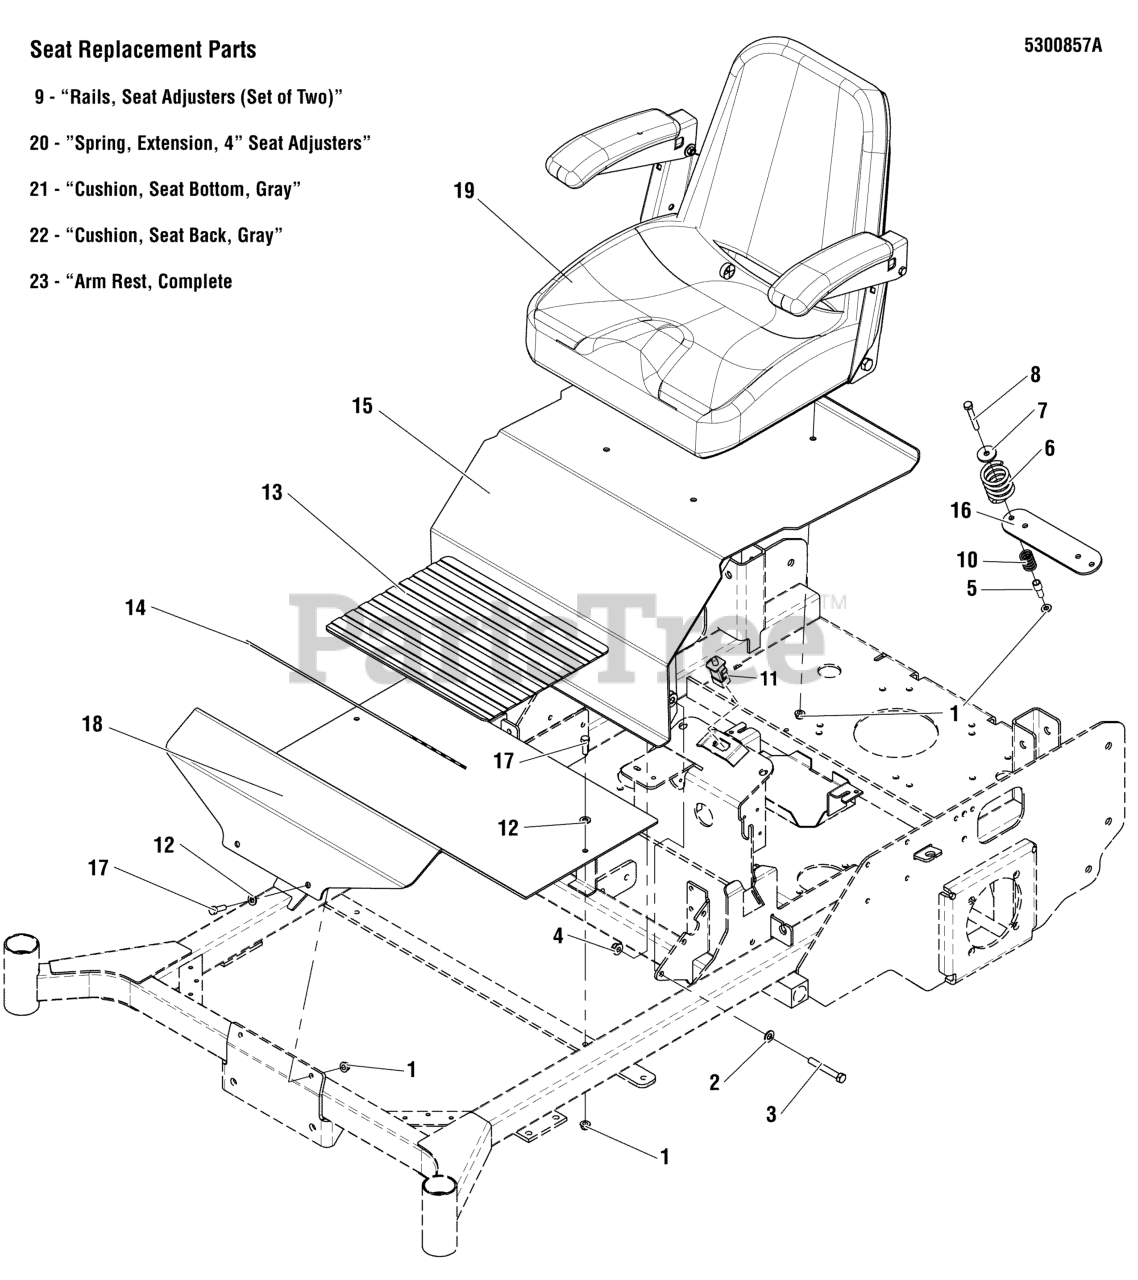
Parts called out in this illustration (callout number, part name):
1	NUT, 5/16-18 HEX NYLOCK FLANGE
2	WASHER, 3/8 SAE
3	BOLT, 3/8-16 X 2, GD5, CZ
4	NUT, 3/8-16 HEX NYLOCK FLANGE
5	SPACER, .328 ID X .66, YZ
6	SPRING, SEAT SUPPORT
7	WASHER, .34 X 1.25 X 10 GA
8	BOLT, 5/16-18 X 2-1/4" GD5 YZ
9	SLIDE RAILS
10	SPRING, COMP 720ID X 1.310LG X .118WIRE
11	SWITCH, PLUNGER, NO/NO SNAP IN
12	WASHER, 5/16" SAE
13	SAFETY WALK, 11.50 X 19.00
14	SAFETY WALK, 10.00 X 19.00
15	ASSM, SEAT PLATE W/ DECALS - S200X
16	PLATE, SEAT SWITCH - RED
17	BOLT, 5/16-18 X 1 GD5 YZ
18	PLATE, FLOOR PAN, S200X - SNAPPER RED
19	SEAT, GRAY, NO LOGO, CMPT
19	SEAT, LOW COMPANION
20	SPRING, EXTENSION, SEAT ADJUSTMENT (YEL OR BLK)
21	CUSHION, SEAT BOTTOM, GRAY (SV)
22	CUSHION, SEAT BACK, GRAY (SV)
23	ARM REST, COMPLETE (SV)
